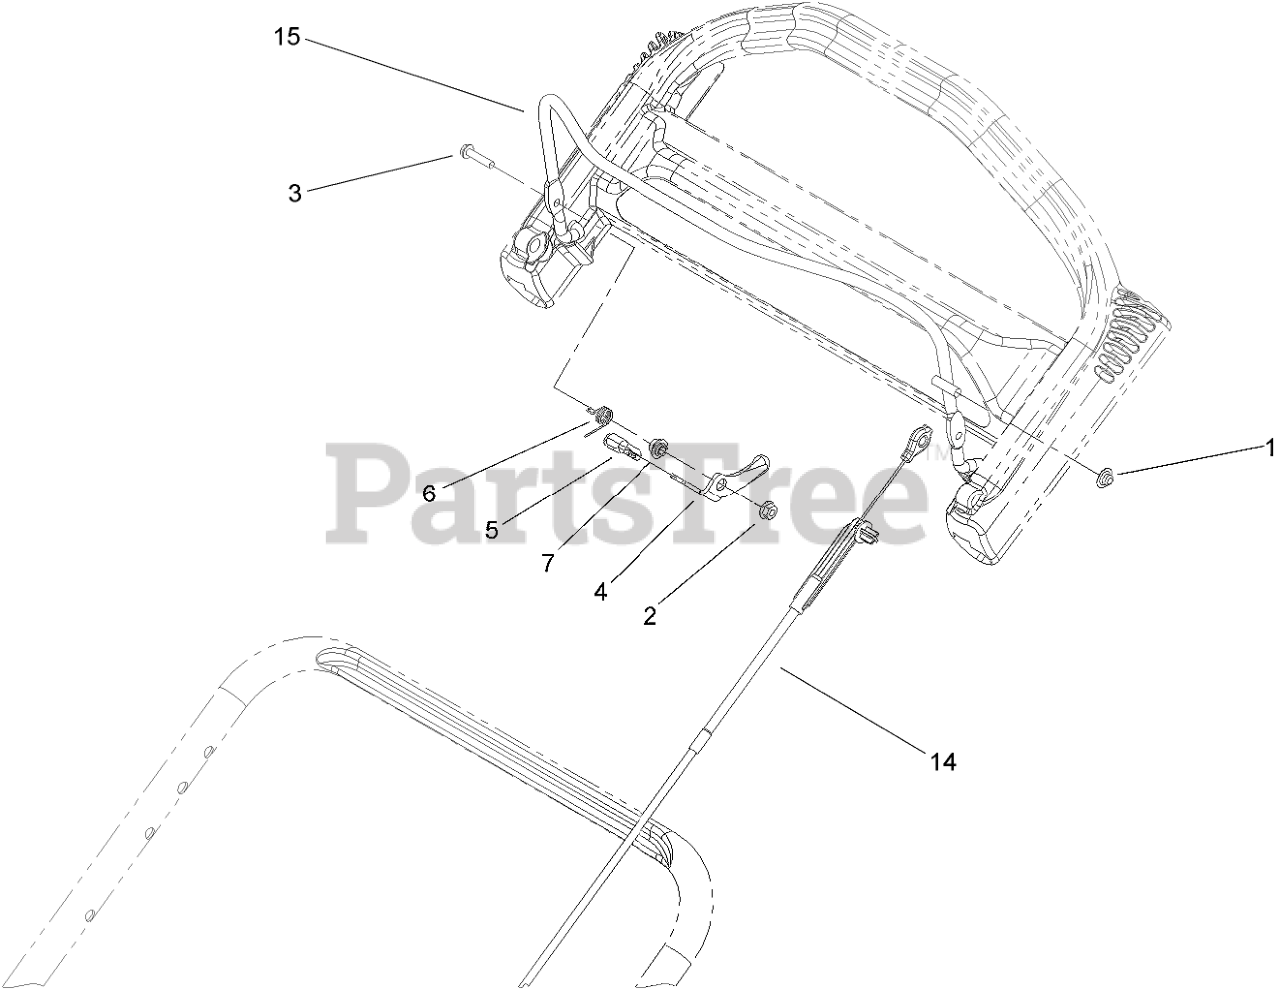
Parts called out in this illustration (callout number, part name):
1	NUT-SPEED
2	NUT-LOCK, FLANGE
3	SCREW-HWH
4	LEVER
6	SPRING-TORSION
7	SPACER
14	CABLE ASM
15	BAIL-BRAKE
